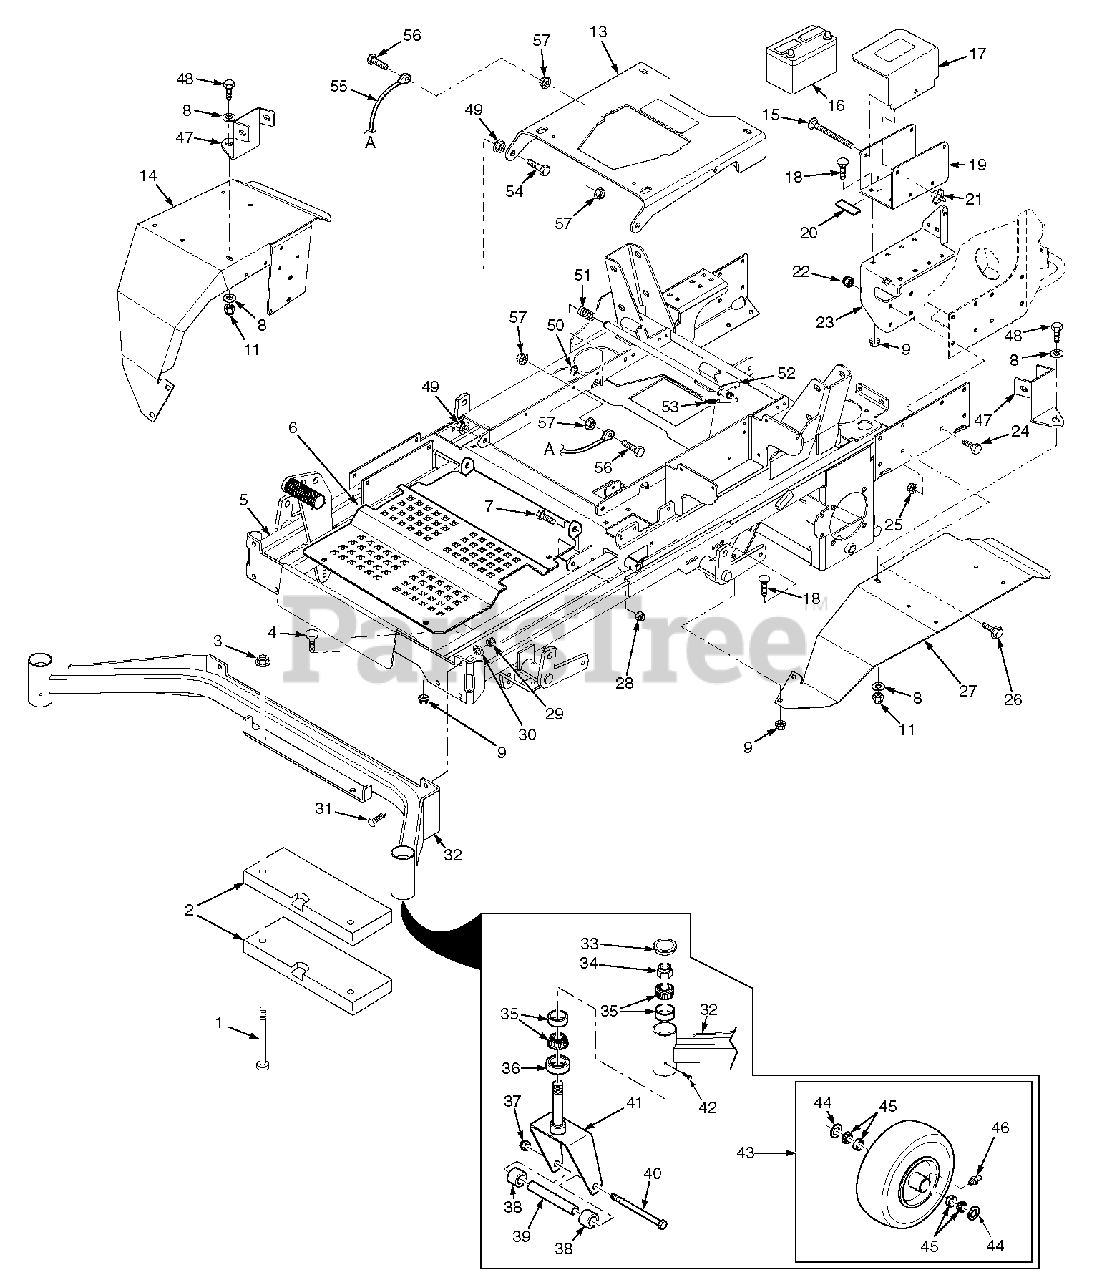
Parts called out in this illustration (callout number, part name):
1	Bolt, Hex Head 1/2-13 x 3.5"
2	Weight
3	Nut, Hex Elastic Stop 1/2-13
4	Bumper, Rubber 5/16-18 x 5/8"
5	Main Frame Assembly w/Decals
6	Foot Plate
7	Bolt, Hex Head 3/8-16 x 1"
8	Flatwasher, 3/8-.391 x .938 x .105
9	Nut, Hex Serrated Flange 5/16-18
10	Bolt, Hex Head 3/8-16 x 2.0"
11	Nut, Elastic Stop 3/8-16
12	Spacer Bushing
13	Seat Plate Weldment w/Decal
14	Fender Weldment, RH
15	Bolt, Carriage 1/4-20 x 6"
16	Battery (not avail. through Scag)
17	Cover, Battery
18	Bolt, Carriage 5/16-18 x 3/4"
19	Plate, Battery Box
20	Rubber Pad
21	Wing Nut, 1/4-20 x 3/4"
22	Nut, Elastic Stop 3/8-16
23	Battery Box Mount
24	Bolt, Hex Head 3/8-16 x 1"
25	Nut, Hex Serrated Flange 3/8-16
26	Screw, Hex Serrated Flange 3/8-16 x 1"
27	Fender Weldment, LH
28	Nut, Hex Elastic Stop 3/8-16
29	Nut, Elastic Stop 7/16-14
30	Lockwasher, 7/16"
31	Bolt, Hex Head 7/16-14 x 1-1/4"
32	Extention Weldment, Caster
33	Cap, Grease
34	Nut, Hex Elastic Stop 1.0"-14
35	Bearing W/Race
36	Seal, 2.00" OD. x 1.625" Bore
37	Nut, Hex Elastic Stop 1/2-13
38	Spacer, Caster Wheel
39	Sleeve, Caster Wheel (61V)
40	Bolt, Hex Head 1/2-13 x 9-1/2" (61V)
41	Yoke Weldment, Caster (61V )
42	Plug, 1/4-28 THD Form
43	Wheel Assembly
45	Bearing w/ Race
46	Grease Fitting
47	Bracket, Fender Support
48	Bolt, Hex Head 3/8-16 x 1-1/4"
49	Nut, 7/16-14 Serrated Flange
50	Retaining Ring .625" Ext. "E"
51	Spring, Seat Latch
52	Lever Assembly, Seat Release
53	Grip, Seat Latch
54	Bolt, Hex Head 7/16-14 x 1-3/4"
55	Cable, Seat Stop
56	Bolt, Hex Head, 1/4-20 x 1-1/4"
57	Nut, Hex Serrated Flange 1/4-20
